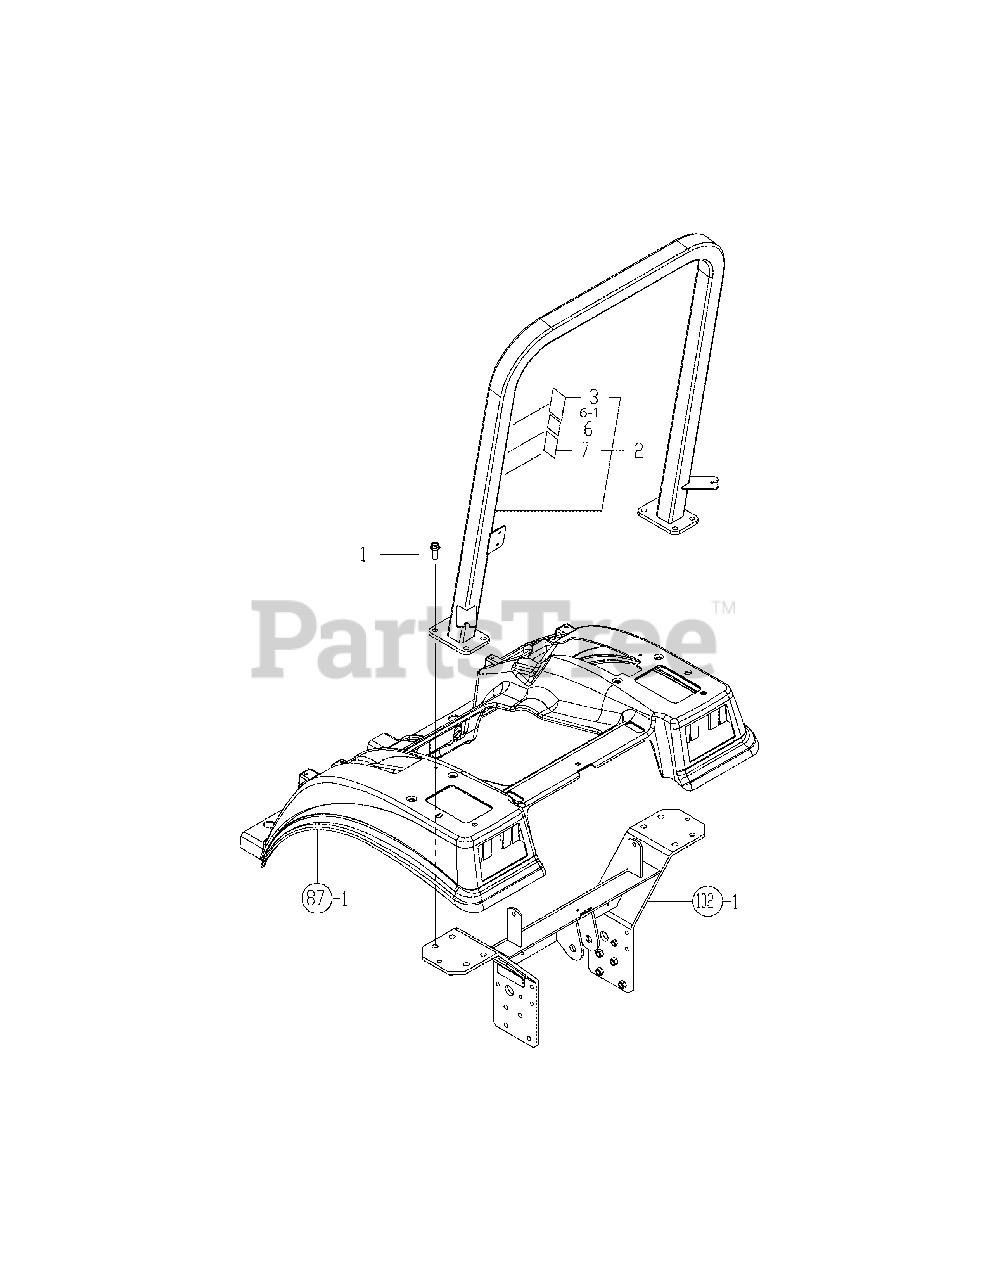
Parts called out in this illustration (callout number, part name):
2	Upper Tube, M Assy
3	Label,Rops
6-1	Safety Decal, Rops
7	Safety Decal (Belt
